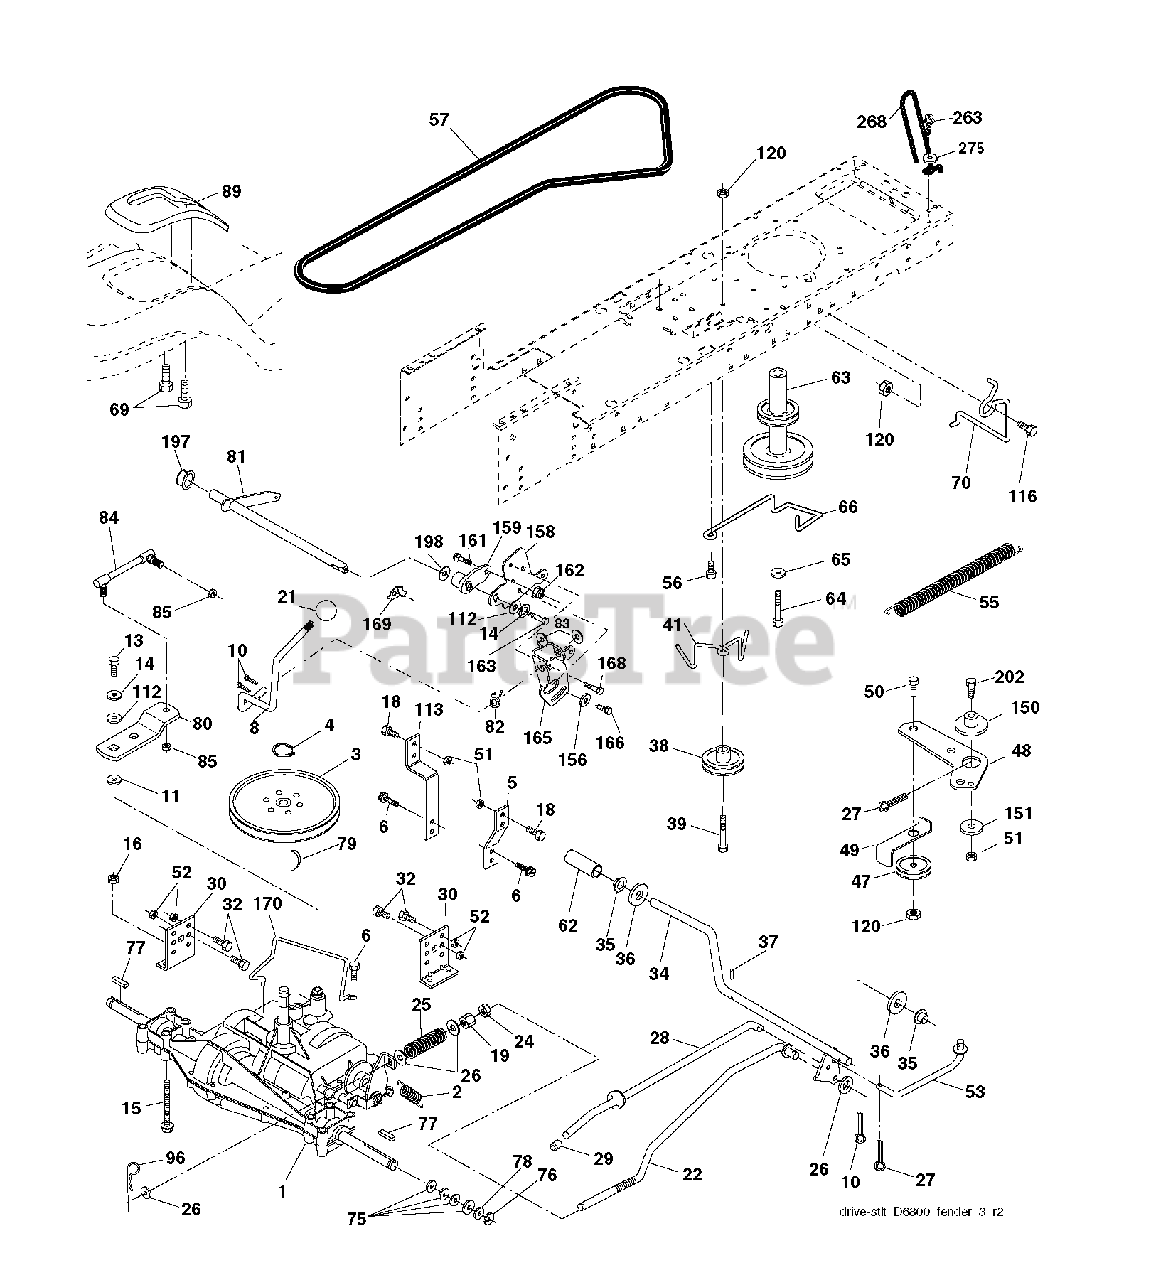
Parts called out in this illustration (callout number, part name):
2	SPRING,BRAKE RETURN
3	PULLEY TRANS
4	RETAINING RING LT
5	STRAP TORQUE
6	SCREW 5/16"
8	ROD SHIFT FENDER ADJUST LT
10	PIN COTTER
11	WASH-SHFT PLT LT
13	BOLT 1/4-28X3/4
14	LOCKWASHER
15	BOLT HEX 5/16-18 GR 5
16	NUT.71038.31-18.HEX.NYLOCK
19	NUT
21	KNOB T (1/2-HOLE)
22	ROD BRAKE
24	NUT
25	SPRING ROD LT
27	COTTER PIN
28	ROD, PARKING BRAKE
29	PLUNGER CAP
30	BRKT, MOUNT TRNSAXLE
32	BOLT
34	SHAFT, FOOT PEDAL
35	BEARING.NYLON
36	WASHER LT
37	DRIVE PIN
38	PULLEY IDLER COMPOSITE
41	KEEPER, BELT IDLER
47	IDLER PULLEY
48	BELLCRANK, CLUTCH
49	RETAIN BELT
50	BOLT.3/8-16X1.50
51	LOCKNUT
52	LOCKNUT
53	LINK.CLUTCH.7.66.2005
55	SPRING, RETURN LT
56	SCREW.3/8-16
62	PEDAL COVER T
63	ENGINE PULLEY
64	BOLT HEX 7/16-20X4-1/4"
65	LOCKWASHER
66	KEEPER BELT ENGINE
69	SCREW.HI-LO.CONSOLE
70	KEEPER BELT ENG
76	E-RING LT
77	SQUARE KEY
82	SHIFT SPRING
83	WASHER
84	LINK.TRANSAXLE.DANA/18
85	NUT LOCK CENTER 1/4 -28 FNTHD
96	RETAINER M
112	WASHER LT
113	STRAP TORQUE LH LT
116	BOLT D
120	NUT LOCK FLG 3/8-16 UNC
150	SPACER, RETAINER
151	WASHER 12/32X2X10GA
156	WASHER.SRRTD.5/16
158	BRACKET
159	HUB.SHIFT
161	BOLT
162	NUT.CROWNLOCK.1/4
165	RP BRACKET
168	BOLT.SHOULDER.5/16-18X
169	PLATE.FASTENING.CROSS.SHAFT
170	KEEPER BELT T/A
197	NYLINER SNAP 5/8" ID
198	WASHER.NYL.7/8IDX.105"HYD CR
202	BOLT
263	SCREW, 3/8-16X3/4
275	WASHER
